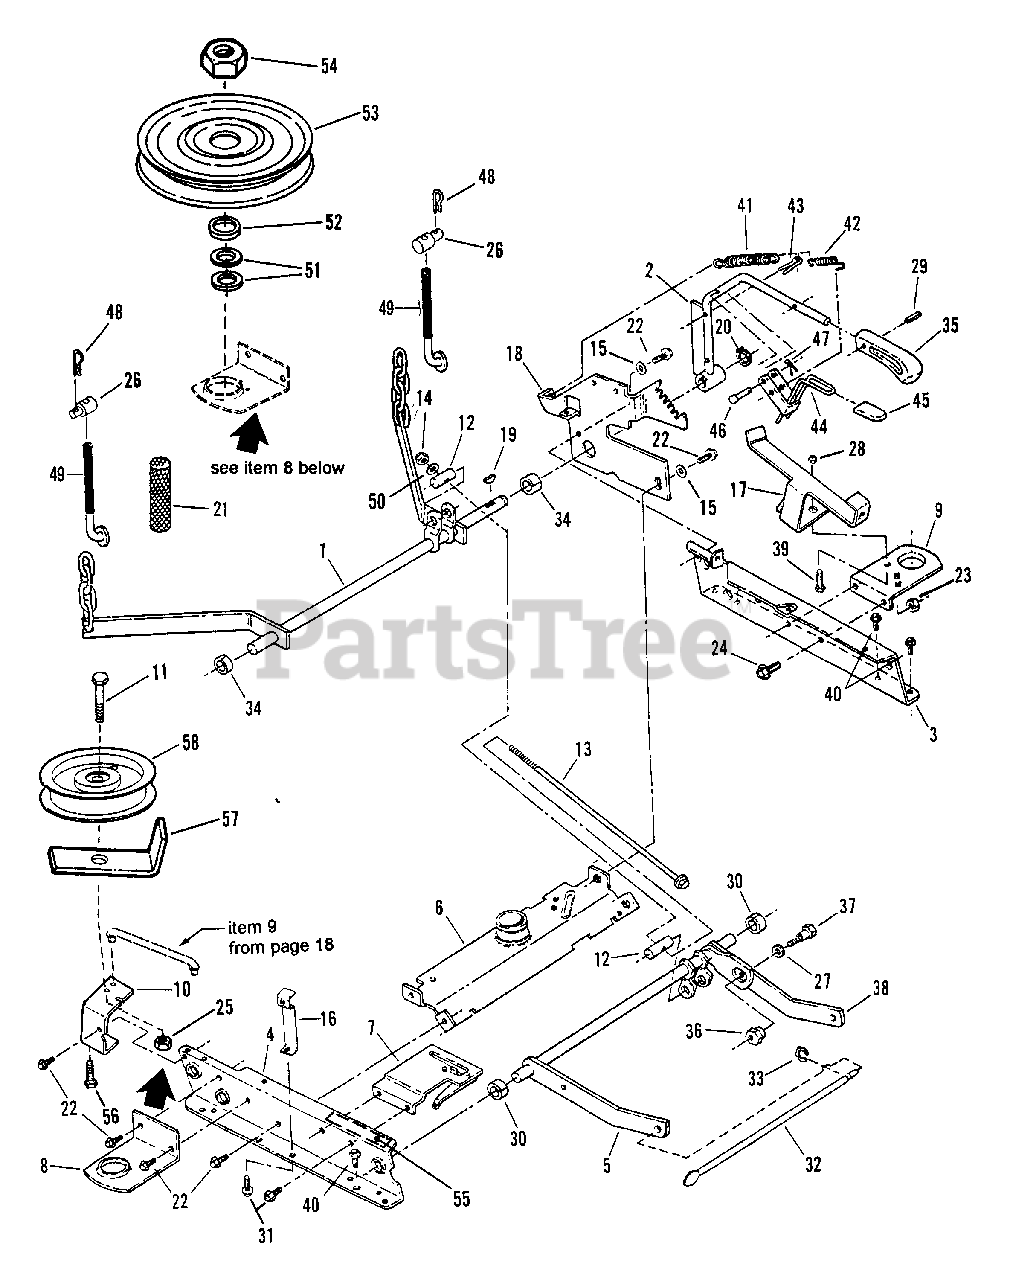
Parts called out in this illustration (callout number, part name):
1	ASSEMBLY, Rear Lift Arm
2	LEVER, Height Adjustment Lift
3	RAIL, Left Half
4	RAIL, Right Half
5	STRUCTURE, Front Lift Arm
6	BRACE, Weldment
7	ASSEMBLY, Clutch Plate
8	SPINDLE, Brace (Right)
9	SPINDLE, Brace (Left)
10	BRACKET, Cover
11	SCREW, 3/8-24 x 1-3/4", Gr. 5
12	PIVOT
13	ROD, Leveling
14	NUT, 3/8-24 Hex Top Lock
15	WASHER, 3/8 Internal Tooth Lock
16	GUIDE, Belt (Rod)
17	GUIDE, Belt 42" RER
18	QUADRANT, Lift Lever
19	KEY, 3/16 x 7/8" Woodruff
20	RING, 3/4 Retaining
21	COVER, Chain
22	SCREW, 3/8-16 x 3/4" Self-Tapping
23	NUT, 3/8-24 Hex Lock
24	SCREW, 3/8-24 x 3/4" Hex Cap
25	NUT, 5/16-24 Hex Center Lock
26	SWIVEL, Adjustable
27	WASHER, 3/8 Internal Tooth Lock
28	NUT, 3/8-24 Hex Lock
29	PIN, 3/16 x 3/4" Roll
30	RING, Red
31	SCREW, 5/16-18 x 1/2" Self-Tapping
32	SUPPORT, Rod
33	RING, Retaining
34	RING, Blue
35	GRIP, Height Adjustment Lever
36	ECCENTRIC, Leveling
37	BOLT, 3/8-24 x 3/4" Shoulder
38	ARM, Front Lift (Left Side)
39	BOLT, 3/8-16 x 1" Hex Flange Lock
40	BOLT, 5/16-18 x 5/8" Hex Flange Lock
41	SPRING, Extension
42	SPRING, Latch
43	PIN, 3/16 x 1-1/2" Cotter
44	LATCH
45	GRIP, Lift Latch
46	PIN, 1/4 x 1-1/4" Clevis
47	PIN, 1/16 x 3/4" Cotter
48	PIN, 3/32 x 1-1/2" Hair Cotter
49	ADJUSTER, Chain
50	WASHER, 3/8" Flat
51	WASHER, 3/4 Flat
52	SPACER, 3/4 I.D.
53	PULLEY, 5" O.D.
54	NUT, 3/4-16 Hex Jam
55	DECAL, Blade On/Off
56	BOLT, 5/16-18 x 5/8" Hex Washer Self-tap
57	GUIDE, Belt
58	IDLER, 4-1/8" Flat
